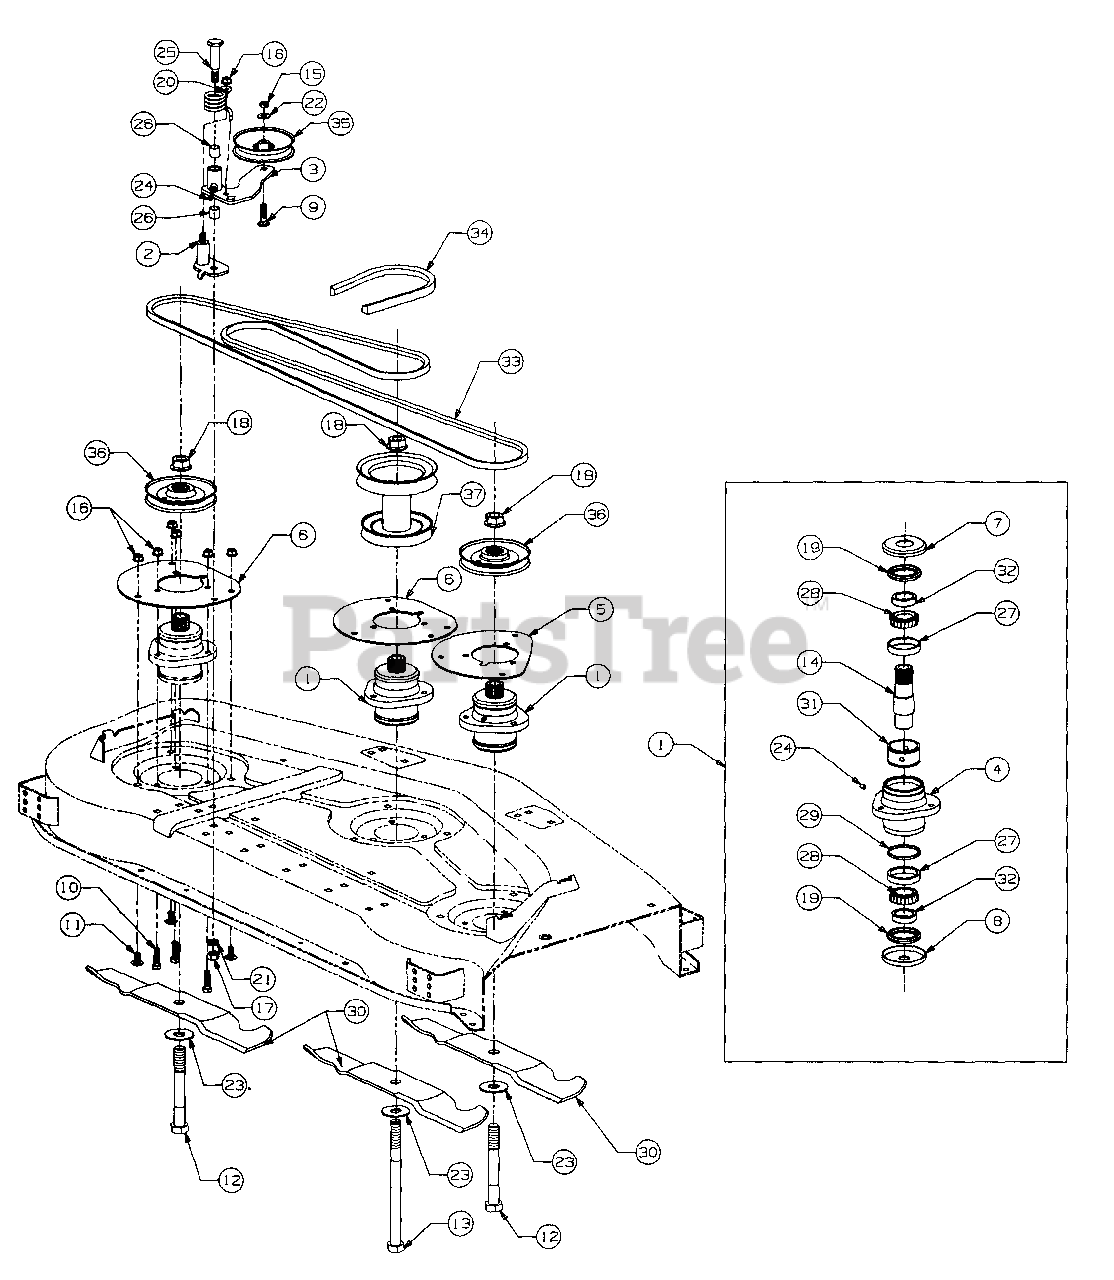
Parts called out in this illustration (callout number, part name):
1	Spindle Assy, Complete
2	Plate, Idler Mtg
3	Arm Assy Idler [Includes Ref No. 24 & 26 (Qty 2)]
4	Housing, Spindle
7	Cup, Top Spindle
9	Bolt, Carriage, 3/8-16 X 1.50 Lg
10	Screw, Hex Cap, 3/8-16 X 1.25 Lg GR5
11	Bolt Sht Nk Carriage,3/8-16 X .75 Lg GR5
12	Bolt, Hex Hd Blade, 3/4-16 X 6.0 Lg
13	Bolt, Hex Hd Blade, 3/4-16 X 9.50 Lg
14	Shaft, Blade Spindle
15	Nut, Hex Center Lock Jam, 3/8-16
16	Nut, Hex Flanged Lock, 3/8-16
17	Nut, Hex, 7/16-14 GR5
18	Nut, Hex Flange, 3/4-16
19	Seal, Oil
20	Spring, Torsion
21	Washer, Lock, 7/16
22	Washer, Flat, .385 X .87 X .06 Thk
23	Washer, Flat, .781 X 2.0 X .105 Thk
24	Fitting, Lube
25	Bolt, Shoulder
26	Bearing, Sleeve
27	Cup, Bearing
28	Cone, Bearing
29	Spacer, Bearing
32	Ring, Seal
33	Belt, Spindle, A-Sect X 122.0 Lg
34	Belt, PTO, B-Sect X 63.04 Lg
35	Pulley, Flat Idler
36	V-Pulley, 4.65 OD
37	Pulley, Deck, 5.07 OD & 5.75 OD
